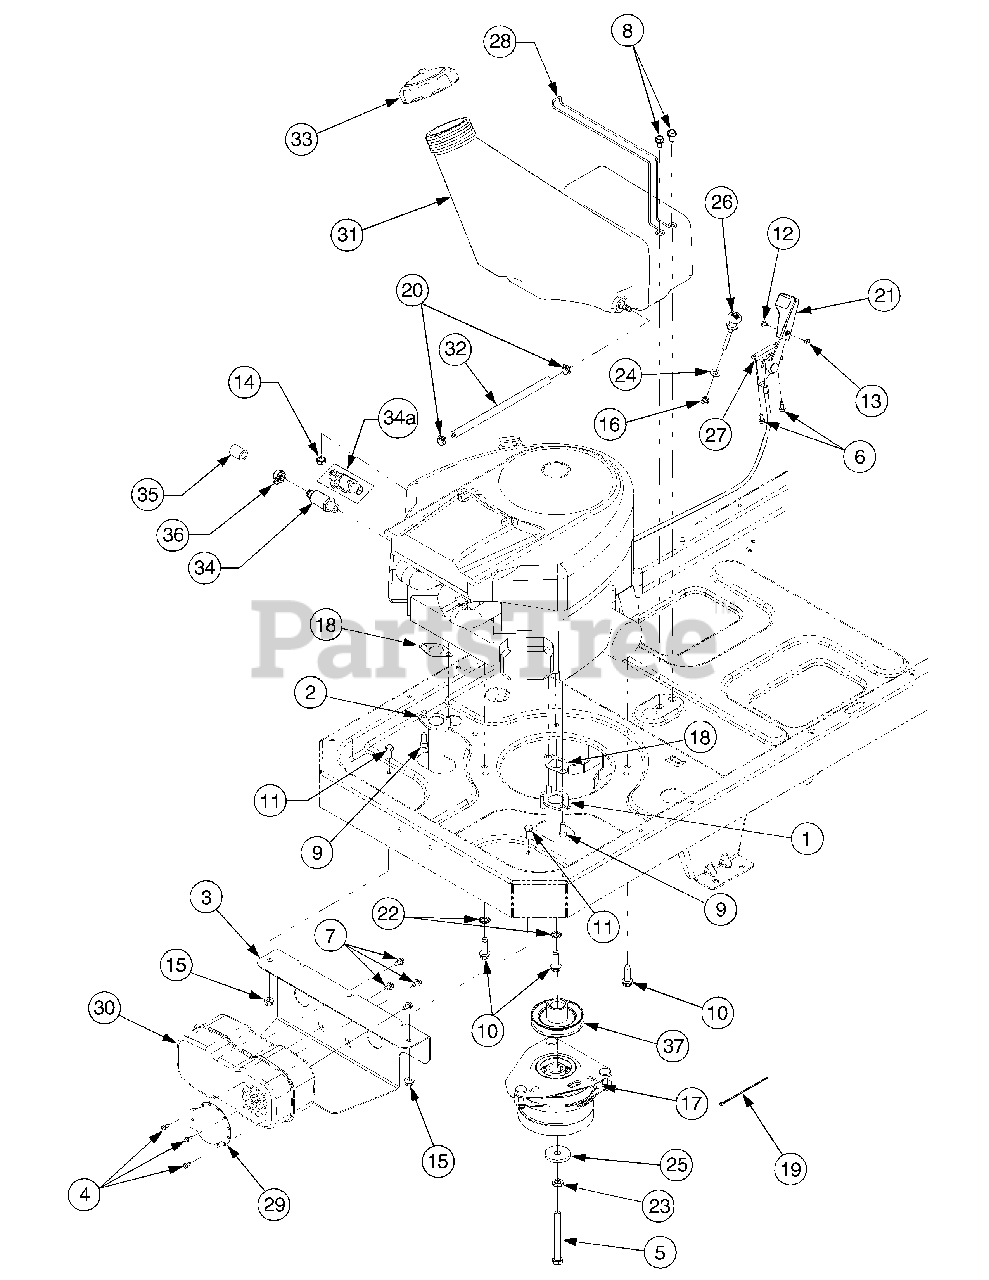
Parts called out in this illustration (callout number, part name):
1	Tube, Exhaust RH
2	Tube, Exhaust LH
3	Bracket, Muffler Mounting
4	Screw, Hex Wash. Hd. Tapp #8-18 x .5
5	Screw, Hex Cap, 7/16-20 x 4.0 GR5
6	Screw, Hex Wash. Hd. Tapp #12-16 x .5
7	Screw, Hex Wash. Hd. Tapp 1/4-20 x .5
8	Screw, Hex Wash. Hd. Tapp 5/16-12 x .75
9	Screw, Socket Hd. 5/16-18 x .75
10	Screw, Hex Wash. Hd. Tapp 3/8-16 x 1.25
11	Screw, Hex Cap, 5/16-18 x .75 GR5
12	Screw, Truss Hd. Mach. #8-32 x .375
13	Nut, Hex, #8-32
14	Nut, Hex Sems, 1/4-20
15	Nut, Hx Insert Flng. Lck., 5/16-18 GR5
16	Nut, Hex Jam, 3/8-16 GR2
17	Clutch Assembly, Electric PTO
18	Gasket, Exhaust
21	Knob, Throttle Control
22	Washer, Ext. Tooth Lock, 3/8
23	Washer, Lock, 7/16
24	Washer, Flat, .406 x .875 x .059
25	Washer, Flat, .438 x 1.75 x .25
26	Cable, Choke, 61Lg
27	Cable, Throttle, 39.0 Lg
28	Wire, Tank Mounting
29	Deflector, Muffler
30	Muffler
31	Tank, Fuel, 3.0 Gal.
32	Hose, Fuel Line 10in
33	Cap, Fuel
34	Valve, Oil Drain - Before Mfg. Code C097
35	Hose, Oil Drain Extension
36	Cap, Oil Drain Valve - Before Mfg. Code C097
37	Pulley, Drive
